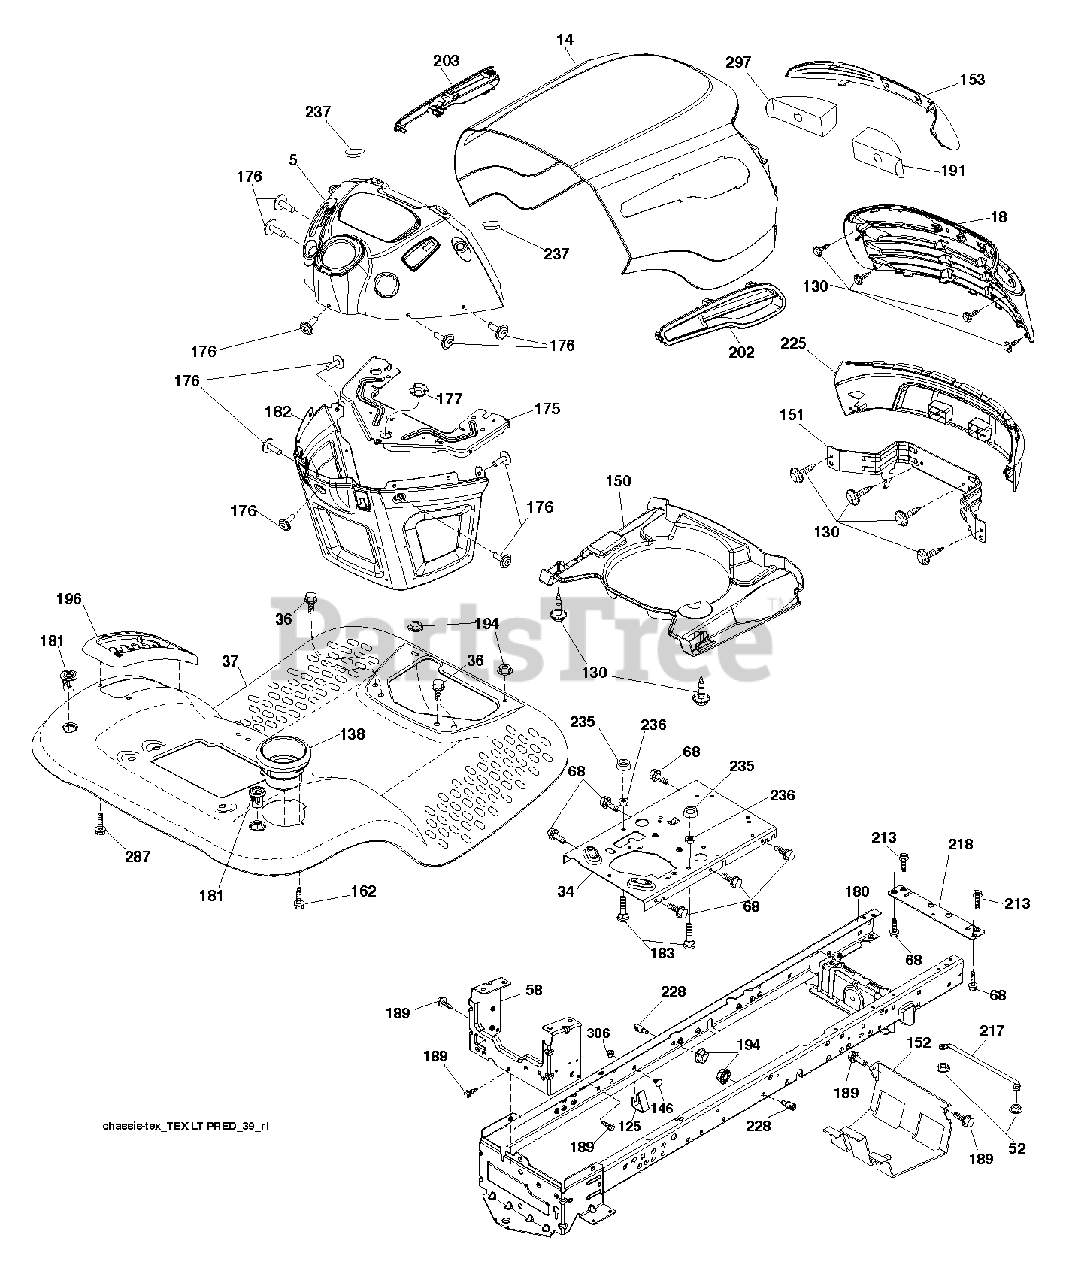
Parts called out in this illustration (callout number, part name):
36	SCREW 5/16"
52	LOCKNUT
58	DRAWBAR UPPER 2PC SMALL FENDER
125	Fuel Line Clip
130	SCREW.#10 X 0.750.BOS THREAD
138	CUPHOLDER.TL.TEX.BLACK
146	BOLT.RDHD.SHT.SQNK.3
151	BRACKET.PIVOT.ALPHA.LT
152	SHIELD BROWNING
153	LENS.PREDATOR.LT
162	SCREW.HI-LO.CONSOLE
175	CROSSMEMBER
176	SCREW.#10-24X5/8.RN.QU
177	BUSHING STEERING
181	FEND/FTRST.PCH.CPH.NFW
182	DASH.LWER.PREDATOR/HUSQ.LT
183	BOLT.5/16-18X1-1/4 FULL THD
189	SCREW
191	INSERT.REFLECT.PREDATOR.LT.RH
194	NUT LOCK HEX FLANGE 5/16-18
196	CONSOLE.ASM.DECKLFT.BL/RBT.TLT
213	BOLT
217	ROD.PIVOT.HOOD
218	X-PIECE.HOOD.STOP.NON/
228	STUD.FASTNER.W/ANTI-ROTATE
235	SPACER FENDER
236	NUT.CENTERLOCK.5/16-
237	PLUG.MOUNT.CARGO.BLK
297	REFLECTOR.INSERT.PRED.LH.LT
306	NUT LOCK FLG 3/8-16 UNC
